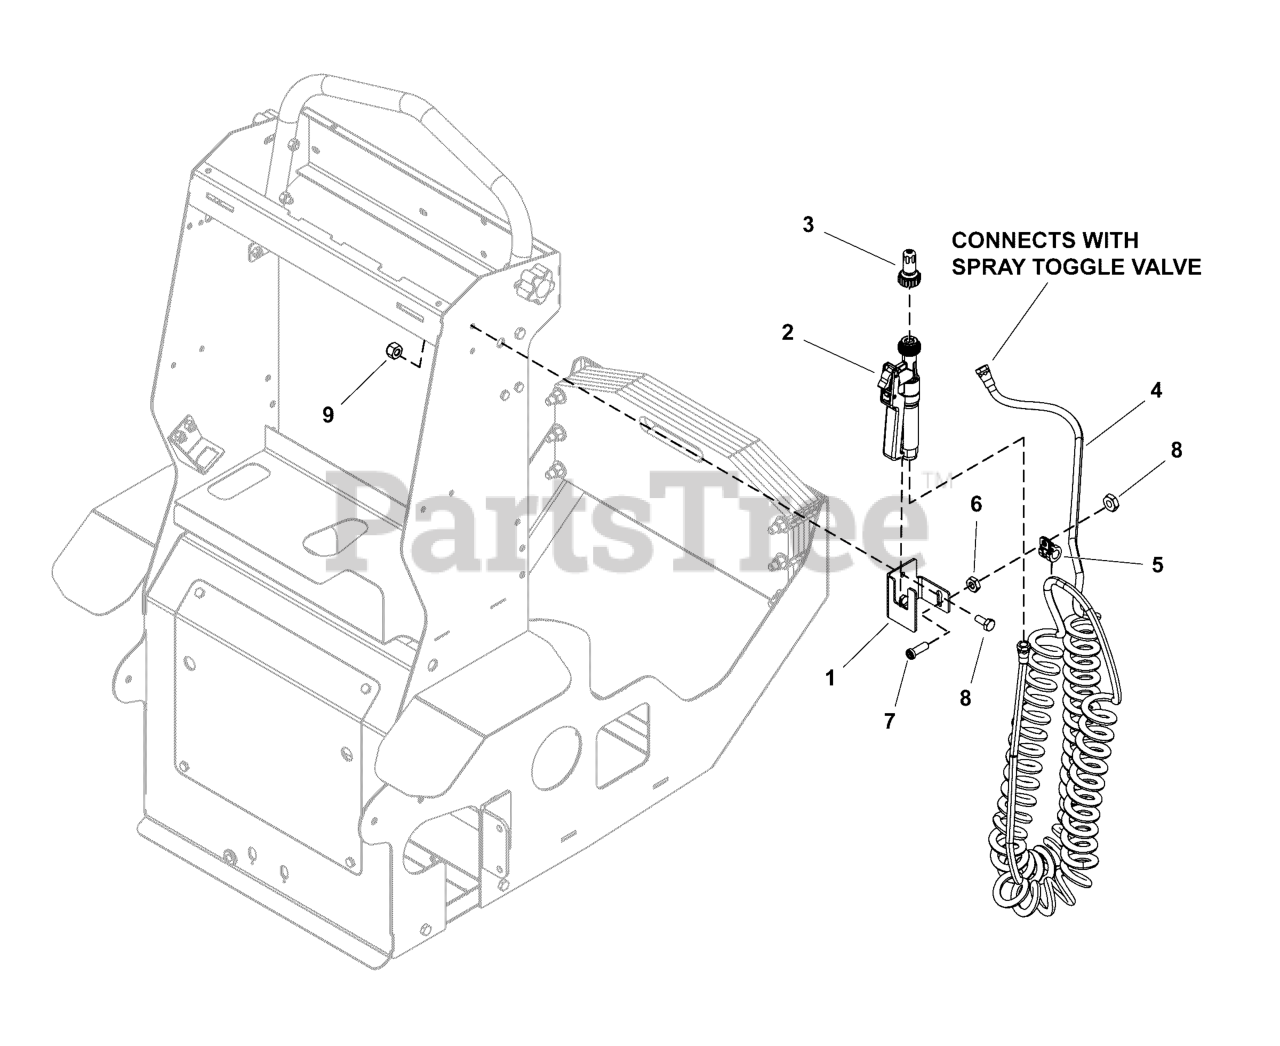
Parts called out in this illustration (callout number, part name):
1	BRACKET, SPRAY WAND HOLDER
2	SPRAY GUN, 1/4 FPT
3	NOZZLE TIP, ADJUSTABLE SPRAY, STANDARD
4	HOSE, COIL 25 FT
5	CLAMP, SPRAY WAND LOOP
6	NUT-HEX, JAM .250"-20 SS188
7	SCR-CAP, SHLP .250-20 X .750" G8 ZP
8	SCR-CAP, HEX .250"-20 X .625" SS188
9	NUT-HEX-NYLK, .250"-20 SS188
